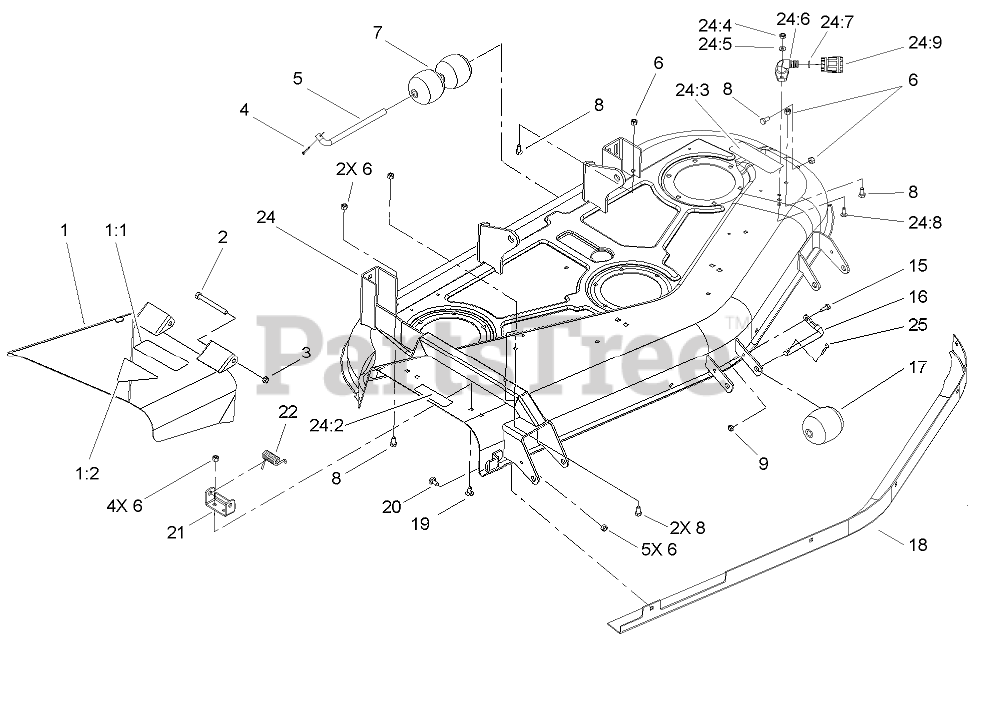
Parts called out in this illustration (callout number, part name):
1	Deflector ASM
1:1	DECAL-DANGER
1:2	DECAL-DANGER
2	SCREW-HH
3	NUT-HEX
4	PIN-COTTER
5	SHAFT-ROLLER, REAR
6	NUT-LOCK, NI
7	ROLLER
8	SCREW-HH
9	NUT-LOCK, NI
15	SCREW-HH
16	Shaft-Roller
17	ROLLER
18	BAFFLE
19	SCREW-CARR
20	BOLT-CARR
21	BRACKET-PIVOT
22	SPRING
24	52IN DECK/DECAL ASM
24:2	DECAL-CAUTION
24:3	DECAL-DANGER
24:4	NUT-LOCK, NI
24:5	WASHER-FLAT
24:6	FITTING-WASHOUT
24:7	O-RING
24:8	BOLT-CARR
24:9	CONNECTOR-HOSE
25	PIN-COTTER
